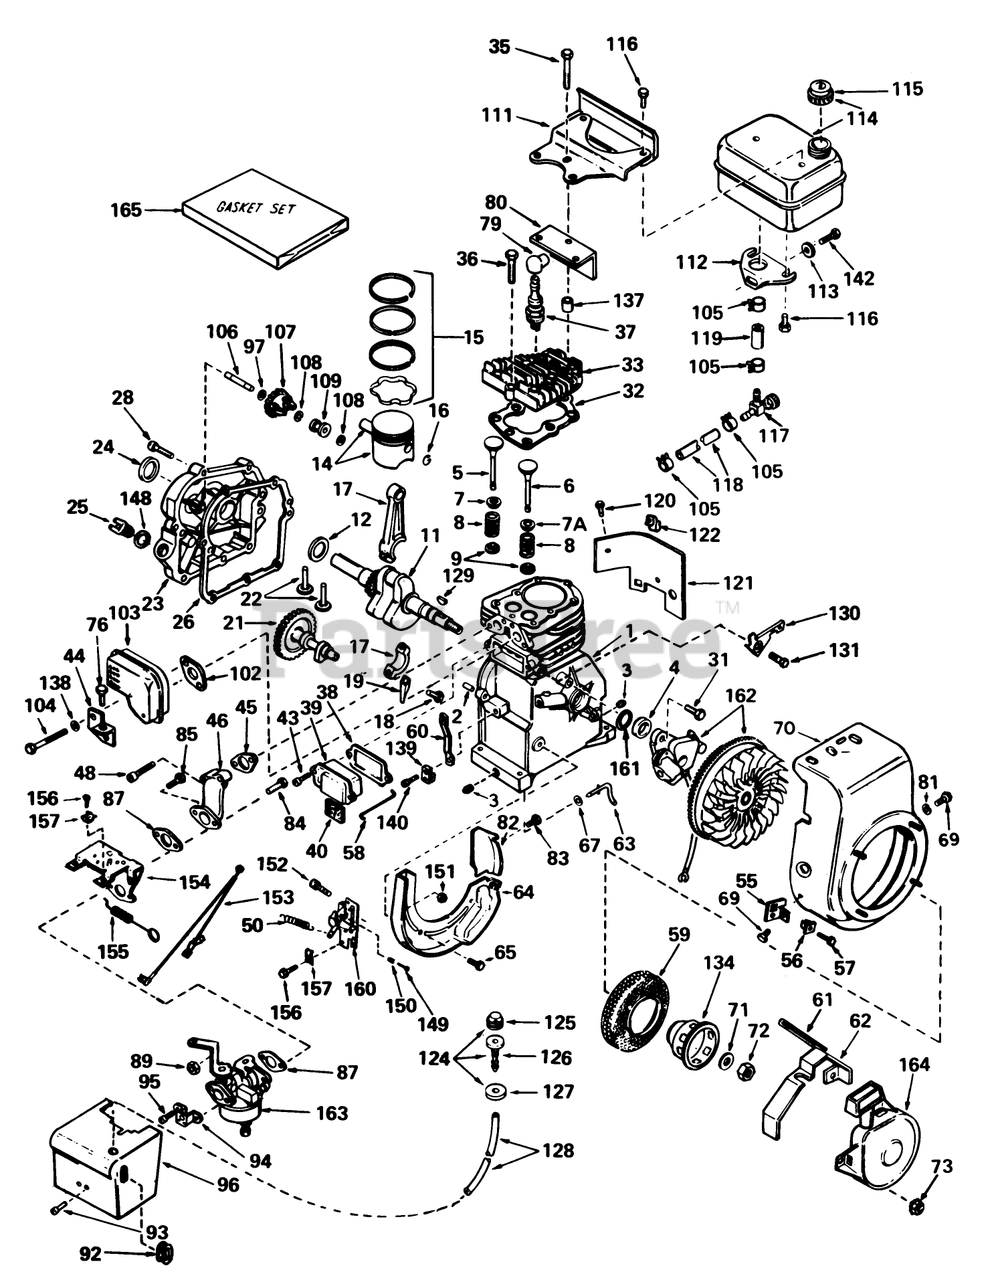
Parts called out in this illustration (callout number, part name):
1	Cylinder Assy. (Incl. Nos.2, 34)
2	Pin-Dowel
3	Plug-Drain, Oil (SQH 1/4-18)
4	Seal-Oil
5	Valve, Intake (Standard) (Incl. Nos. 7, 9 10)
5	Valve, Intake (1/32" Oversize) (Incl. Nos. 7, 9 10)
6	Valve, Exhaust (Standard) (Incl. Nos. 8, 9 10)
6	Valve, Exhaust (1/32" Oversize) (Incl. Nos. 8, 9 10)
7	Cap-Upper Valve Spring
7A	Cap, Upper Valve Spg (Exhaust)
8	Spring-Valve
9	Cap-Valve, Spring
11	Crankshaft Assy.
12	Washer-Thrust
14	Piston Pin Assembly (Incl. 2 of No. 14)(Std.)
14	Piston Pin Assembly (Incl. 2 of No. 14)(.010 Oversize)
14	Piston Pin Assembly (Incl. 2 of No. 14)(.020 Oversize)
15	Ring Set-Piston Std.
15	Ring Set-Piston .010 oversize
15	Ring Set-Piston .020 oversize
16	Ring-Retaining, Piston Pin
17	Rod Assy., Connecting (Incl. Nos. 18 19)
18	Bolt-Rod, Connecting
19	Dipper-Oil
21	Camshaft
22	Lifter-Valve
23	Cover, Cylinder (Incl. Nos. 24, 25, 106 148)
24	Seal-Oil
25	Plug-Fill, Oil
26	Gasket-Cylinder Cover
28	Screw
31	Screw
32	Oil Fill Tube
33	Head Cylinder
35	Screw (5/16-18 X 2)
36	Screw (5/16-18x1-1/2)
37	Plug, Spark (J17LM or equiv.)
37	Plug, Spark (Champion RCJ-8)
38	Gasket Breather
39	Breather Assembly (Incl. Nos. 52 84)
40	Element-Breather
43	Screw
44	Bracket-Cover, Carburetor
45	Gasket-Intake
46	Pipe-Intake
48	Screw (1/4-20 x 1-19/32)
50	Spring-Extension
55	Bracket
56	Grommet
57	Screw
58	Link-Governor to Throttle
59	Screen-Starter
60	Lever, Governor
61	Seal, Snowguard
62	Guard-Starter
63	Rod-Governor
64	Baffle-Blower Housing
65	Screw (1/4-20x19/32)
67	Washer-Flat
69	Screw
70	Housing, Blower
71	Washer-Spring
72	Hex Nut
73	Nut and Lock Washer (1/4-28)
76	Screw (10-24 x 3/8)
79	Cover-Spark Plug
80	Baffle-Heat
81	Washer
82	Baffle-Extension
83	Screw-Hex Washer Hd.
85	Screw-Fil. Hd.
87	Gasket
89	Nut and Lock Washer (1/4-28)
92	Grommet, Carburetor cover
93	Screw (8-32 X 5/16)
94	Bracket-Choke
95	Screw (10-32 x 1/2)
96	Cover, Carburetor
97	Washer-Flat
102	Gasket-Exhaust
103	Muffler
104	Screw-Fil. Hd.
105	Clamp-Line, Fuel
106	Shaft-Governor
107	Governor Gear ASM
108	Ring-Retaining
109	Spool-Governor
111	Plate-Fuel Tank
112	Bracket, Fuel Tank Lower
113	Washer
114	53023/VAR.10/16HP O
115	Cap, Fuel
116	Screw (1/4-15x7/8)
117	Valve-Shut Off
118	Line-Fuel
119	Line-Fuel (8.62)
120	Screw
121	Extension-Blower
122	51004 GIL ROTARY TI
124	Primer Assy. (Incl. Nos. 89, 90 91)
125	Bulb, Primer
126	Body, Primer
127	Retainer, Primer Bulb
128	Line, Primer
129	Key, FIywheel
130	Bracket-Hold Down
131	Screw, Hex Hd. w/Conical
134	Cup, Starter
137	pacer
138	Washer
139	Clamp-Lever, Governor
140	Screw
142	Screw Assembly
148	Gasket
149	Screw
150	Spring-Compression
151	Nut-Lock
152	Screw
153	Wire-Ground
154	Bracket, Speed Control
155	51011/13 TILL.O/P'7
156	Screw (10-32 x 3/8)
157	Conduit
160	Bracket Assy., Control (Incl. Ref. #149 thru 152 154)
161	Gasket Stator
162	Magneto
163	Carburetor (Incl. 1 of No. 87)
164	Starter Assy., Rewind
165	Gasket Set
